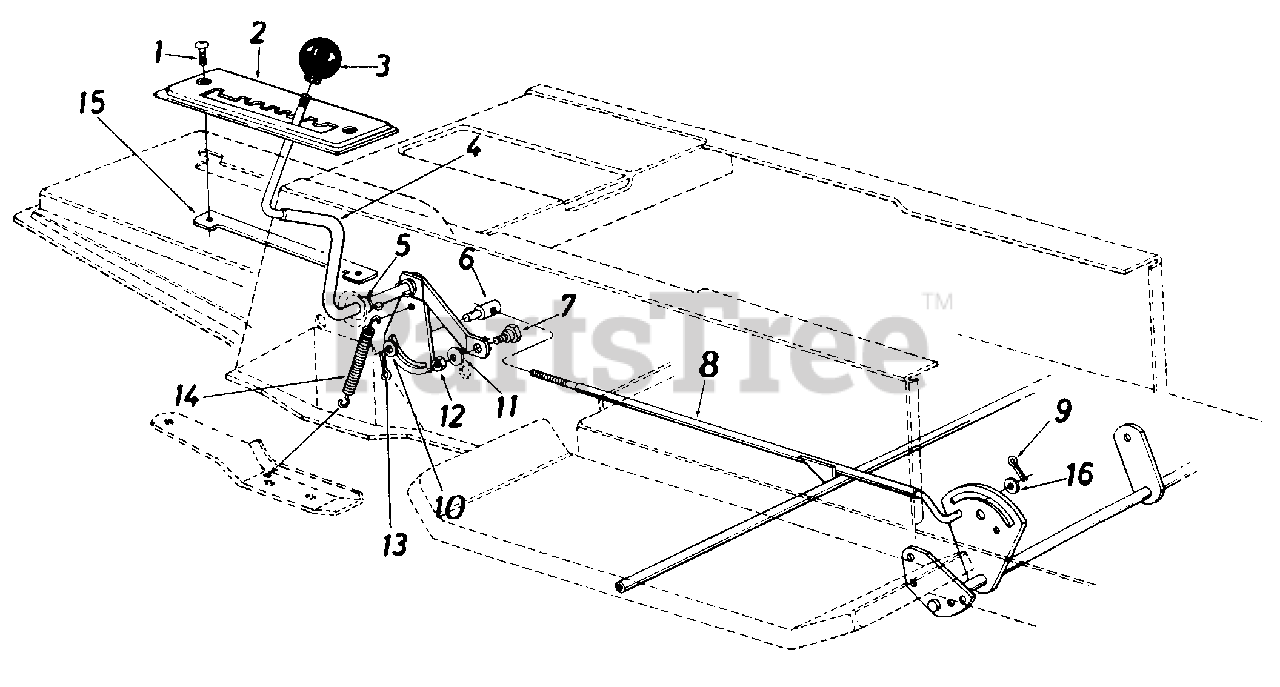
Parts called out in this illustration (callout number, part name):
1	Truss Mach. Scr. 1/4-20 x .75"Lg.
3	Gear Shift Knob
4	Speed Selector Cam Ass'y.
5	Flat Washer .53" I.D. x .93" O.D.
6	Ferrule 3/8-24 x .37" Dia.
7	Shoulder Bolt .435" Dia. x .160
8	Speed Control Rod Ass'y
9	Cotter Pin 3/32" Dia. x .75" Lg.*
10	Fl-Wash. .39" I.D.
11	L-Wash. 5/16" I.D.
12	Hex Nut 5/16-18 Thd.*
13	Hairpin Cotter 1/8" Dia.
14	Spring
15	Clamping Plate
16	Fl-Wash. .47" I.D. x .88" O.D. x .063
